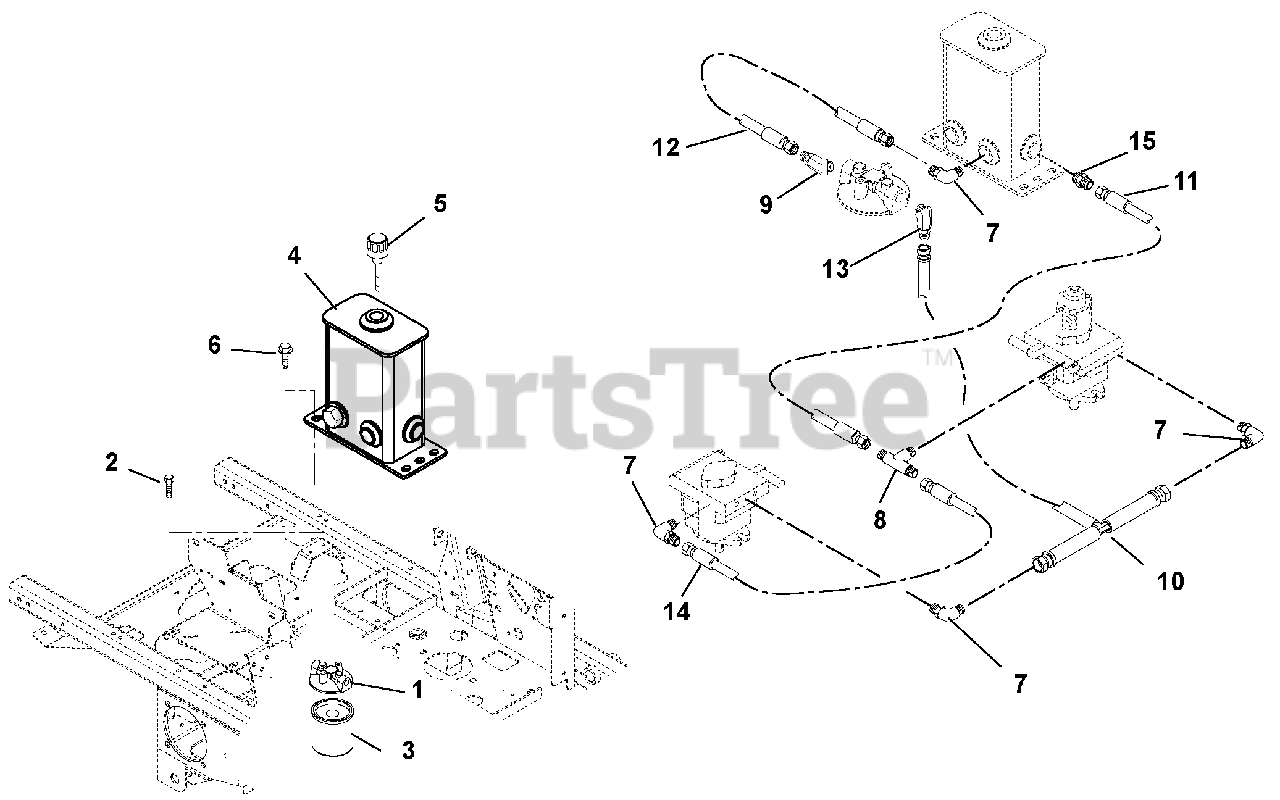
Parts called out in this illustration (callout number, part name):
1	Head, Filter
2	Bolt, Hex .25-20 x .50 Epoxy Grade 5
3	Oil Filter with Bypass
4	Weldment, Formed Hydraulic Tank – 2 Port
5	Dipstick, Breather
6	Screw, Tapping Hex Washer Head .38-16 x .75
7	Fitting, Hydraulic, 90 Degree Elbow, Steel M8F – M80
8	Fitting, Hydraulic Tee M80 – M80 – M80
9	Fitting, Hydraulic Straight M80 – M80
10	Hose, Tee Assembly, .50
11	Hose, Hydraulic .50-19 – 0K FO8J0 – FO8J0
12	Hose, Hydraulic Molded
13	Fitting, Hydraulic 45° M80 – M80
14	Hose, Hydraulic
15	Adapter, Face Seal 8 x 8 .50 O-Ring 8 F5OLO – Steel
